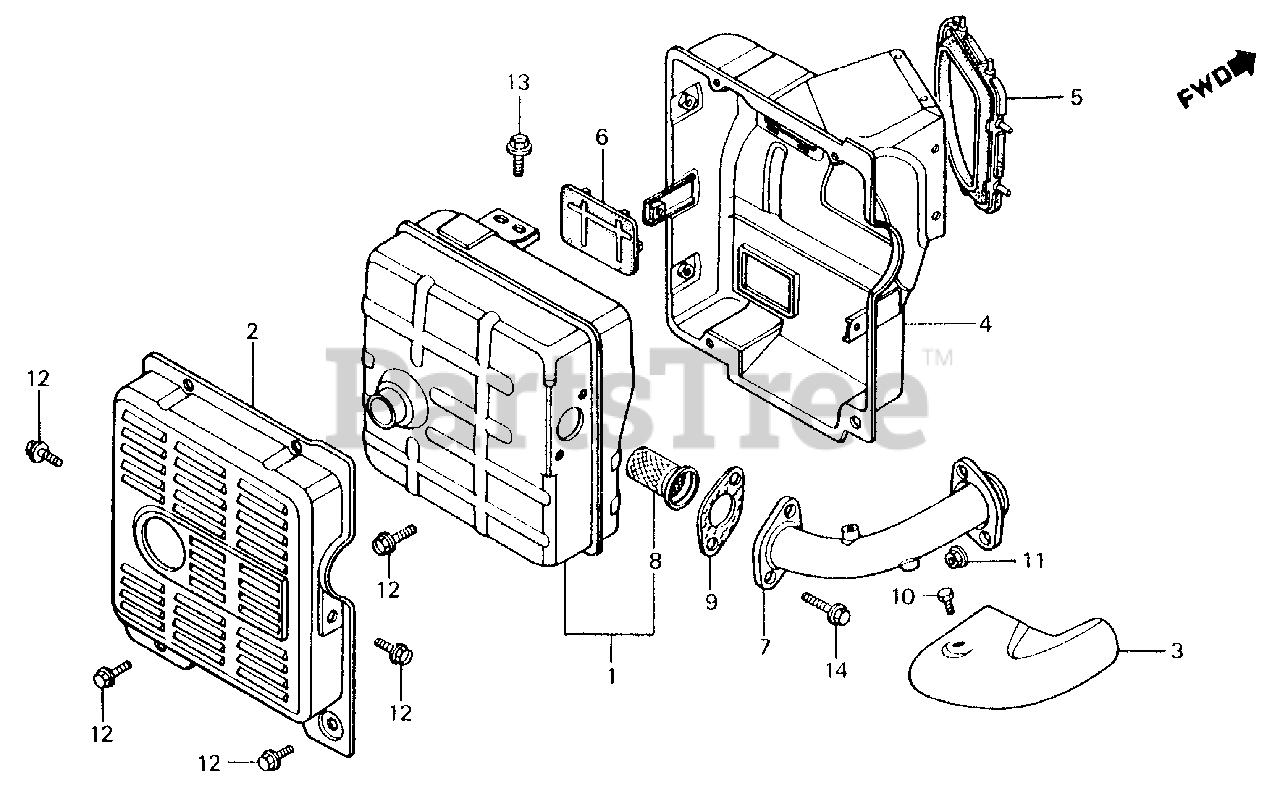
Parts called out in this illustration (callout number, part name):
1	MUFFLER (NOT AVAILABLE)
2	PROTECTOR, MUFFLER (OUTER)
3	PROTECTOR, EX. PIPE
4	PROTECTOR, MUFFLER (INNER)
5	RUBBER, PROTECTOR (INNER)
6	SEAL, MUFFLER PROTECTOR
7	PIPE, EX. (NOT AVAILABLE)
8	ARRESTER, SPARK
9	GASKET, EX. PIPE
10	BOLT, HEX. (6X8)
11	NUT, FLANGE (8MM)
12	BOLT, FLANGE (6X10)
13	BOLT, FLANGE (8X16)
14	BOLT, FLANGE (8X20)
